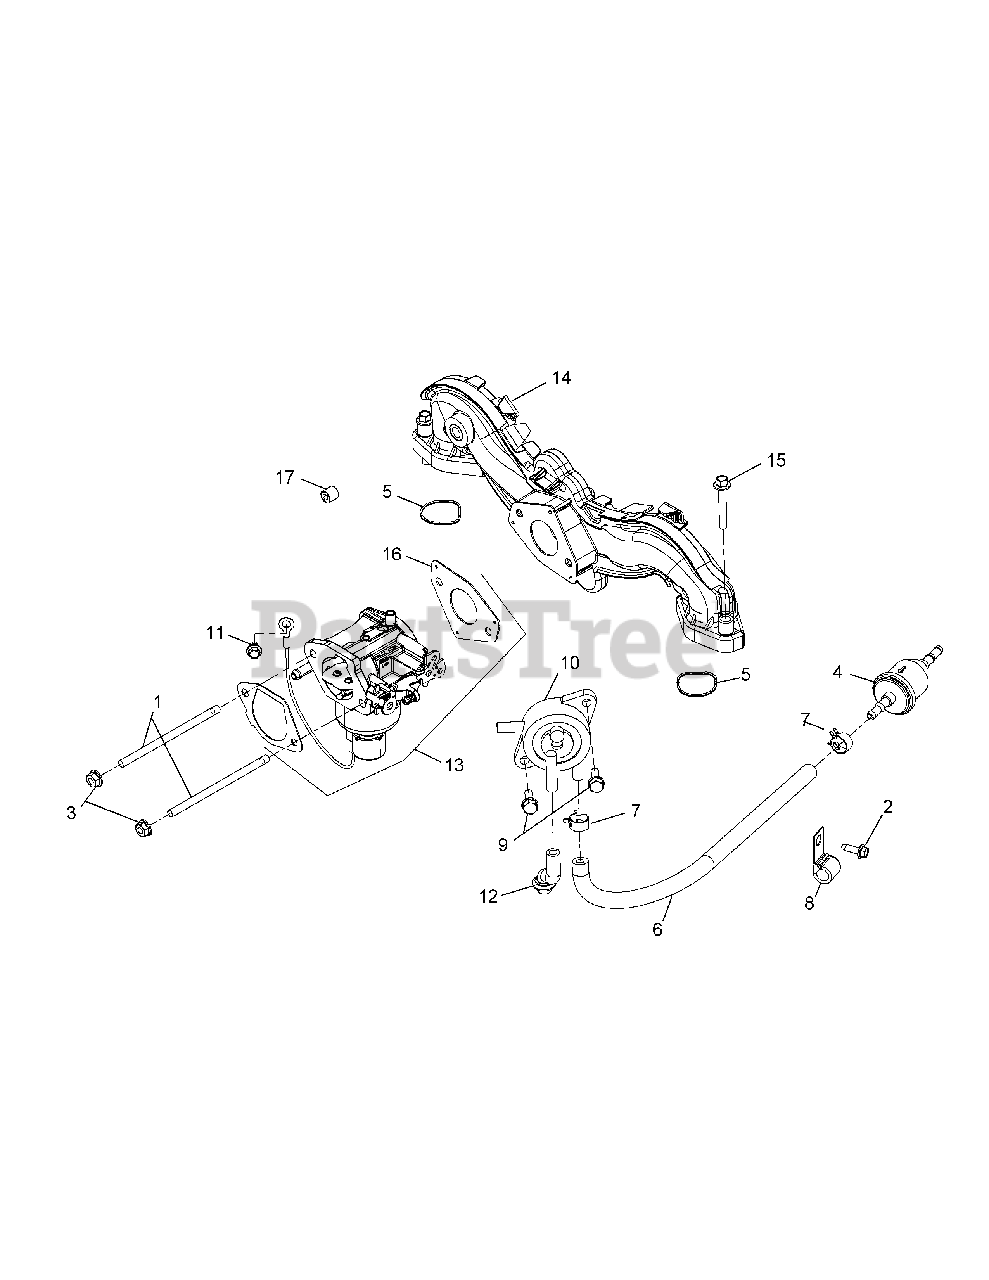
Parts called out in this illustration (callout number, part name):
2	Thread Forming Screw
3	Flange Nut, M6 x 1.0
5	Intake Port O-Ring
6	Fuel Line, 24"
7	Spring Hose Clamp
9	Tap Screw, M6 x 1.7 x 18
11	Thread Forming Screw
12	Pulse Pump Hose
13	Carburator Kit
14	Intake Manifold Kit
15	Flange Screw, M6 x 1.0 x 40
16	Carburetor Gasket
17	Pipe Plug, 1/8
